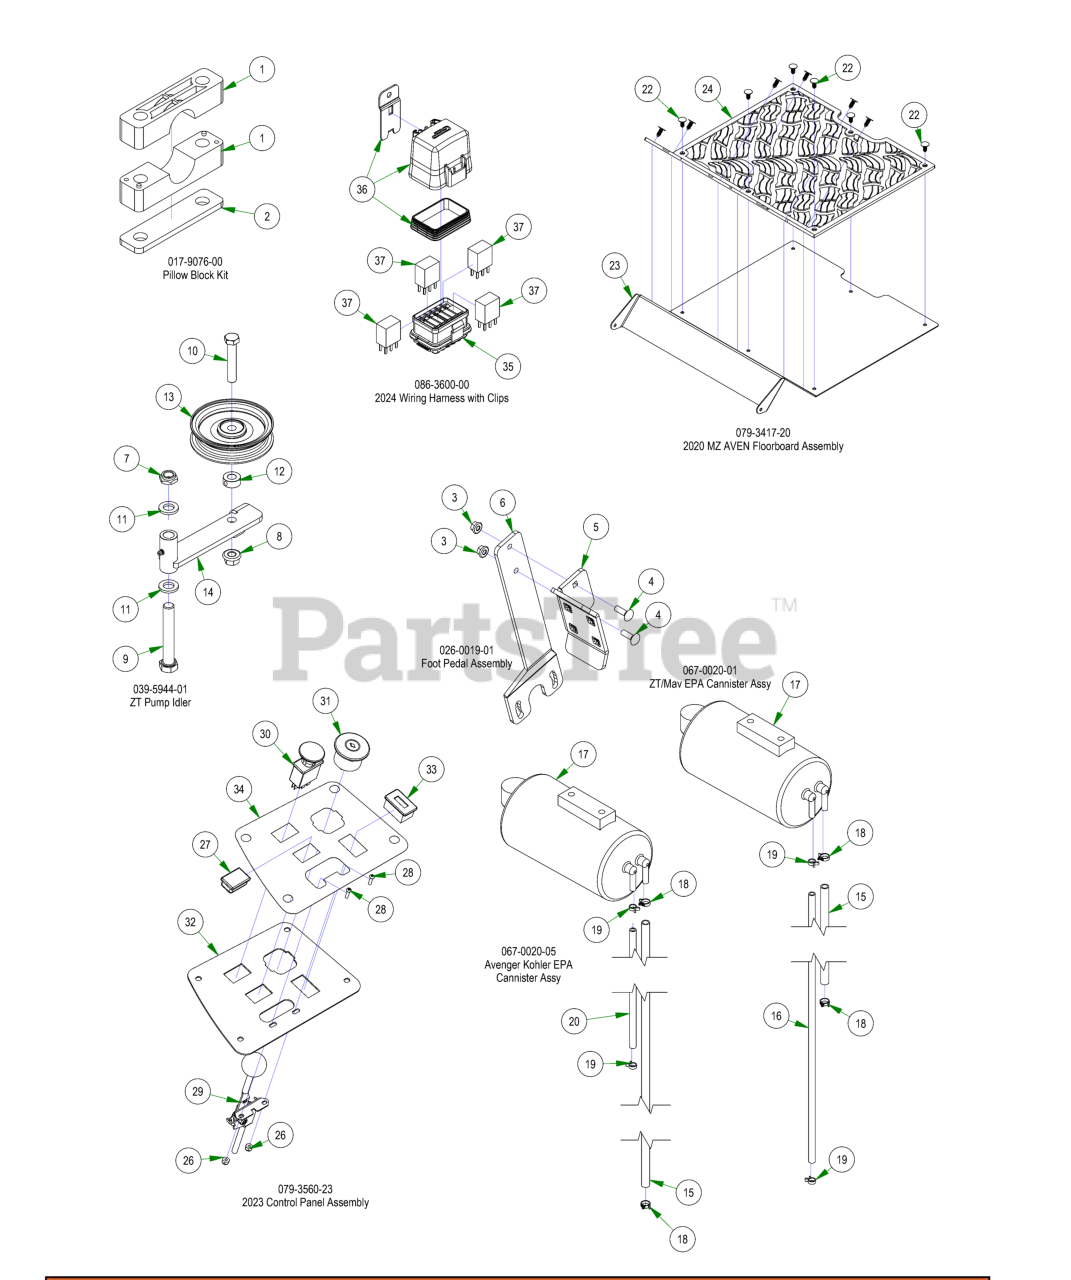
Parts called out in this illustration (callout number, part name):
1	Pillow Block MZ
2	Pillow Block Strap
3	5/16-18 NYLON INSERT FLANGE LOCKNUT ZINC
4	5/16-18 X 1 CARRIAGE BOLT (GR.8) ZINC
5	2017 MZ/ZT Shallow Foot Pedal
6	2017 MZ/ZT Deck Pedal Lever
7	5/8-11 NYLON INSERT JAM LOCKNUT ZINC
8	1/2-13 NYLON INSERT FLANGE LOCKNUT ZINC
9	5/8-11 X 4 HEX CAP SCREW (GR.8) ZINC YELLOW
10	1/2-13 X 2-3/4 HEX CAP SCREW (GR.5) ZINC
11	.635 ID X 1.120 OD X .140 THICK FLAT WASHER NYLON
12	1/2 SOLID SHAFT COLLAR (W/1 SET SCREW) ZINC
13	4 3/4" Idler Pulley
14	Pump Idler Bracket
15	1/4" Vinyl Tubing, 46" Long
16	3/16" Vinyl Tubing, 55" Long
17	Carbon Canister
18	3/16 Vinyl Clamp
19	3/16" Vinyl Hose Clamp
20	3/16" Vinyl Tubing
21	2020 MZ AVEN Floorboard Assembly
22	Ratchet Fastener
23	MZ/ZT 2017 Floorboard
24	2021 Maverick Floor Mat W/ Reaper Tread
25	2023 Control Panel Assembly
26	10-24 Nylon Insert Locknut Zinc Orange Nylon
27	Light Plug
28	10-24 X 5/8 BS Button Head Bolt
29	Throttle Lever Assembly
30	PTO Engager
31	Ignition Switch
32	2022 Maverick HD control panel
33	Tachometer
34	2023 MZ/Magnum/ZT/Maverick Control Panel Decal
35	2024 Wiring Harness with Clips
36	Relay Block Cover Replacement Kit
